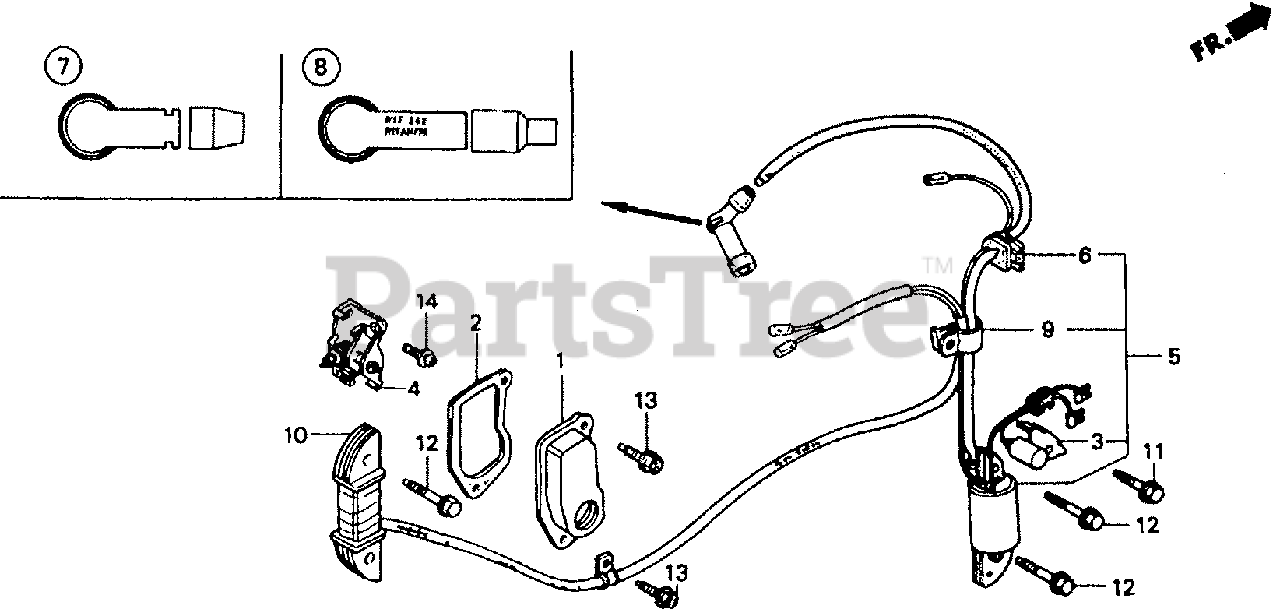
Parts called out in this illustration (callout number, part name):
1	COVER, POINTS
2	GASKET, COVER
3	CONDENSER
4	POINTS ASSY.
5	COIL ASSY., IGNITION (LAMP COIL)
6	GROMMET, WIRE
7	TERMINAL ASSY., IGNITION
8	CAP ASSY., NOISE SUPPRESSOR
9	CLAMP, IGNITION WIRE
10	COIL ASSY., CHARGE (SILICON RECTIFIER)
11	BOLT, FLANGE (6X12) (CT200)
12	BOLT, FLANGE (6X32)
13	BOLT, FLANGE (5X10)
14	SCREW-WASHER (5X12)
